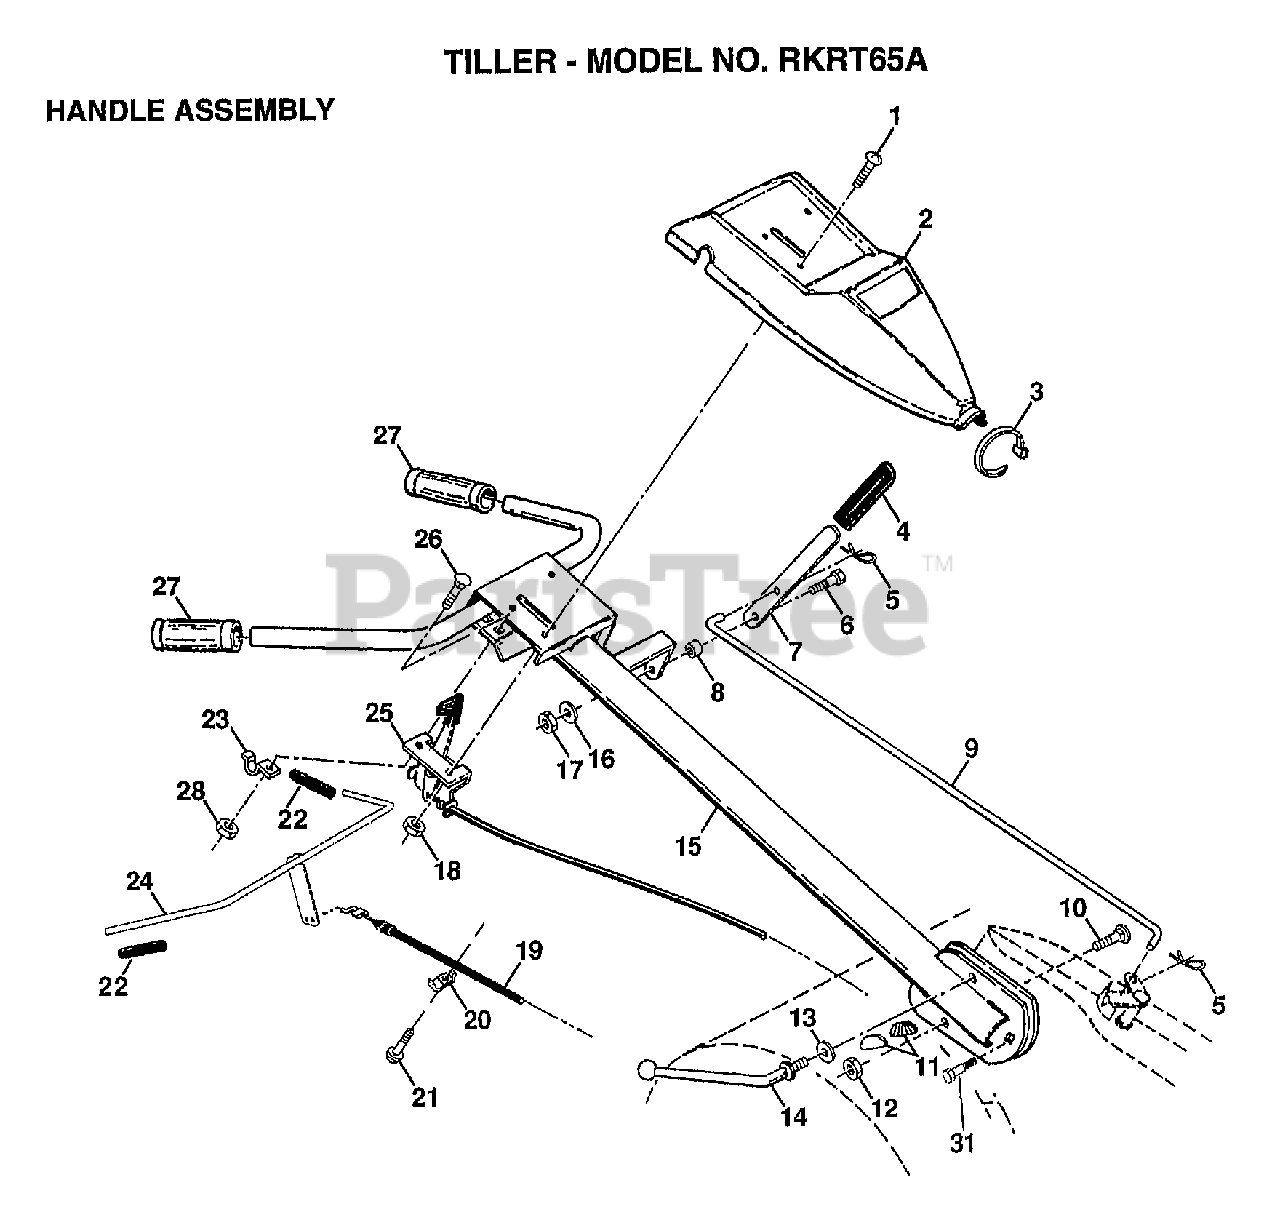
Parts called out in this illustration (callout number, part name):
1	SCREW.PNHD.10-24
2	"PANEL,CONT TI"
3	TIE CABLE CRT
4	GRIP T
5	RETAINER M
6	SHOULDER BOLT ST
7	SHIFT HANDLE CRT
8	GROMMET CRT
9	SHIFT ROD CRT
10	BOLT D
11	LOCK CRT
12	LOCKNUT
13	WASHER CRT
14	LEVER LOCK CRT
16	LOCKWASHER
19	CABLE.CLUTCH
20	CONDIUT CLIP T
22	GRIP BAR CRT
24	BAR ASM CONTROL
25	CONTROL.THROTTLE
26	BOLT
28	NUT
29	BOLT PIVOT
